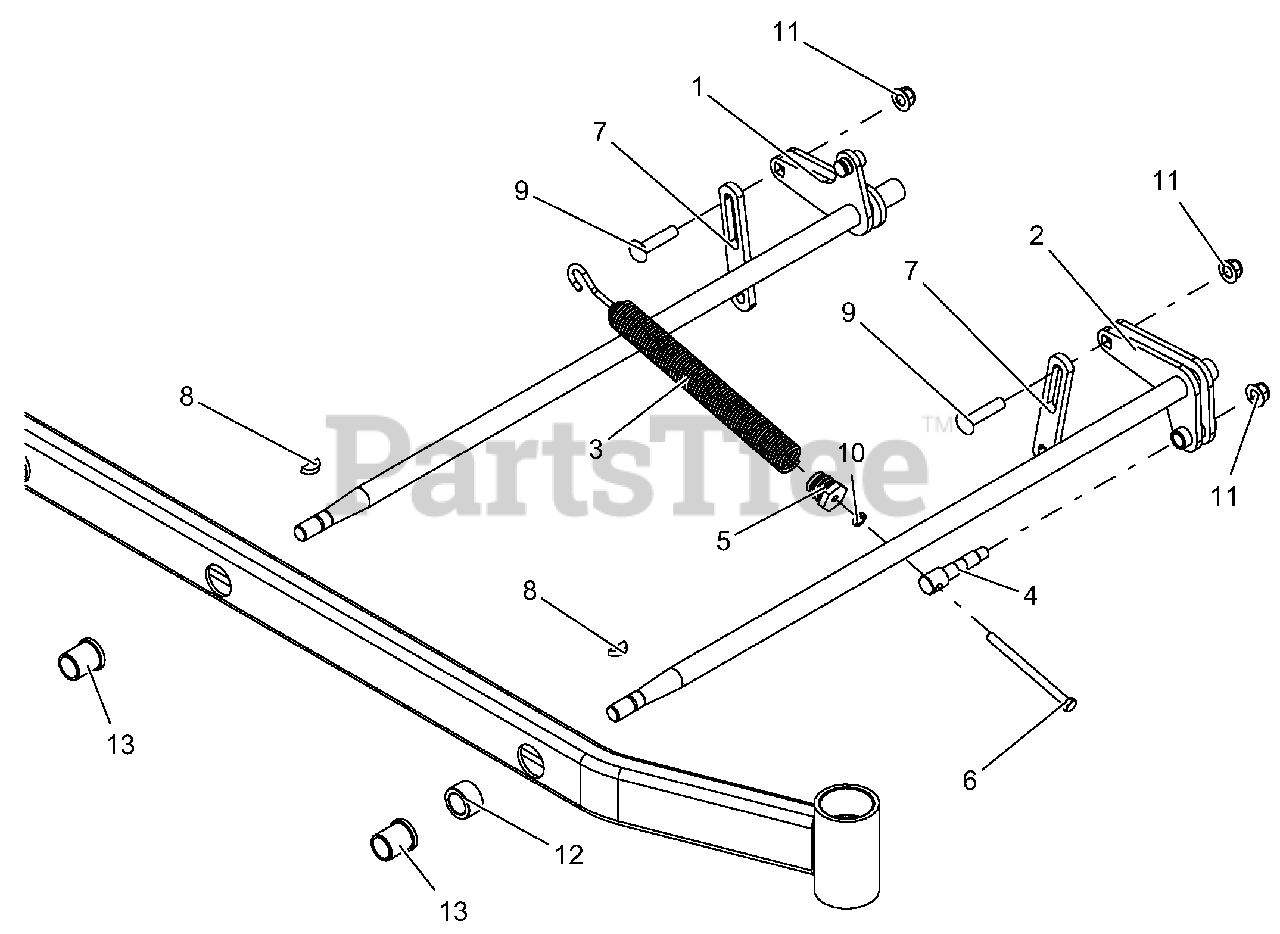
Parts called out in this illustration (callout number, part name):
1	WLDMT, REAR LH DECK LIFT ARM-BLACK
2	WLDMT, FRONT LH DECK LIFT ARM-BLACK
3	SPRG, DECK LIFT
4	TRUNION, SPRG
5	PLUG, SPRG
6	BLT-HEX .38-16X5.00 GR5 YWZC
7	LINK, DECK LIFT - LONG
8	KEY, WDRF .25 X 1.00 HRD #15
9	BLT-RDHDSQNK .50-13X2.25 G5 Y
10	NUT, JAM .375-16 YWZC
11	NUT-LK-NYL-FLG .50-13 YWZC
12	SPACER, 1.500 X 1.000 X .880
13	BSHG-FLG 1.00X1.25X1.5X1.5
